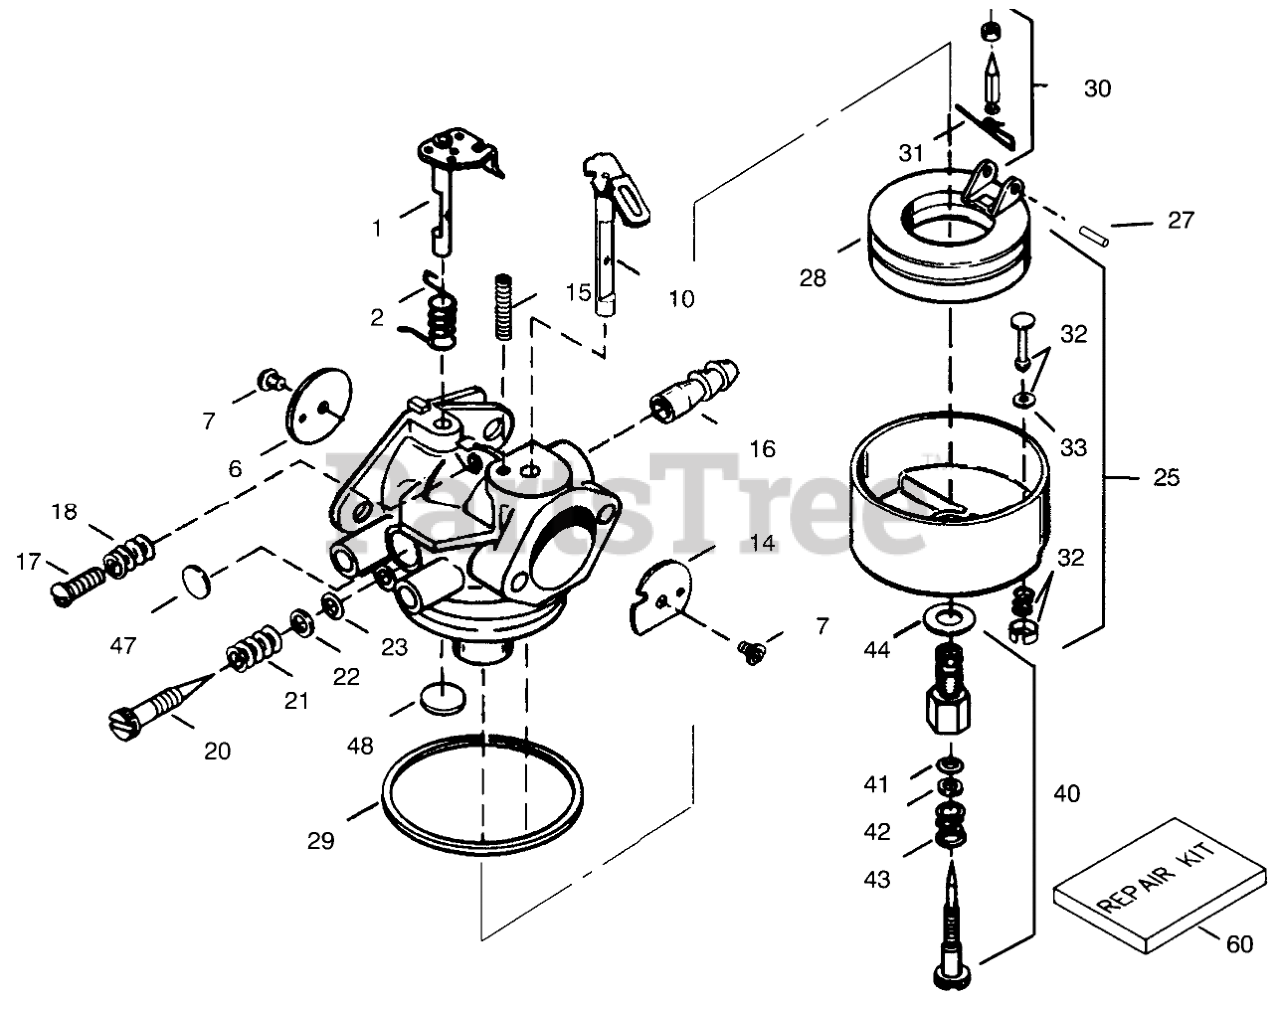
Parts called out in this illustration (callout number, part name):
1	Throttle Shaft and Lever ASM
2	Spring-Return, Throttle
6	Shutter-Throttle
7	Screw-Shutter
10	Choke Shaft and Lever ASM
14	Shutter-Choke
15	Spring-Positioning, Choke
16	Fitting-Fuel
17	Screw-Throttle Crack Screw / Idle Speed
18	Spring-Tension
20	Screw-Idle Mix
21	Spring-Tension
23	"O"Ring
25	Float Bowl Assembly (Incl. Ref. #32 & 33)
27	Shaft-Float
28	Float
29	O Ring-Bowl, Float
30	Inlet Needle, Seat & Clip Asm (Incl. Ref. #31)
31	Clip-Spring
32	Drain Assembly (Incl. Ref. #33)
33	Gasket-Plunger, Drain
40	Adjustment Screw Asm (Incl. Ref. #43, 44, 41 & 42)
41	"O"Ring
44	Washer-Bowl Nut
47	Plug-Welch, Idle Mixture Well
48	Plug-Welch, Atmospheric Vent
60	Kit-Repair
